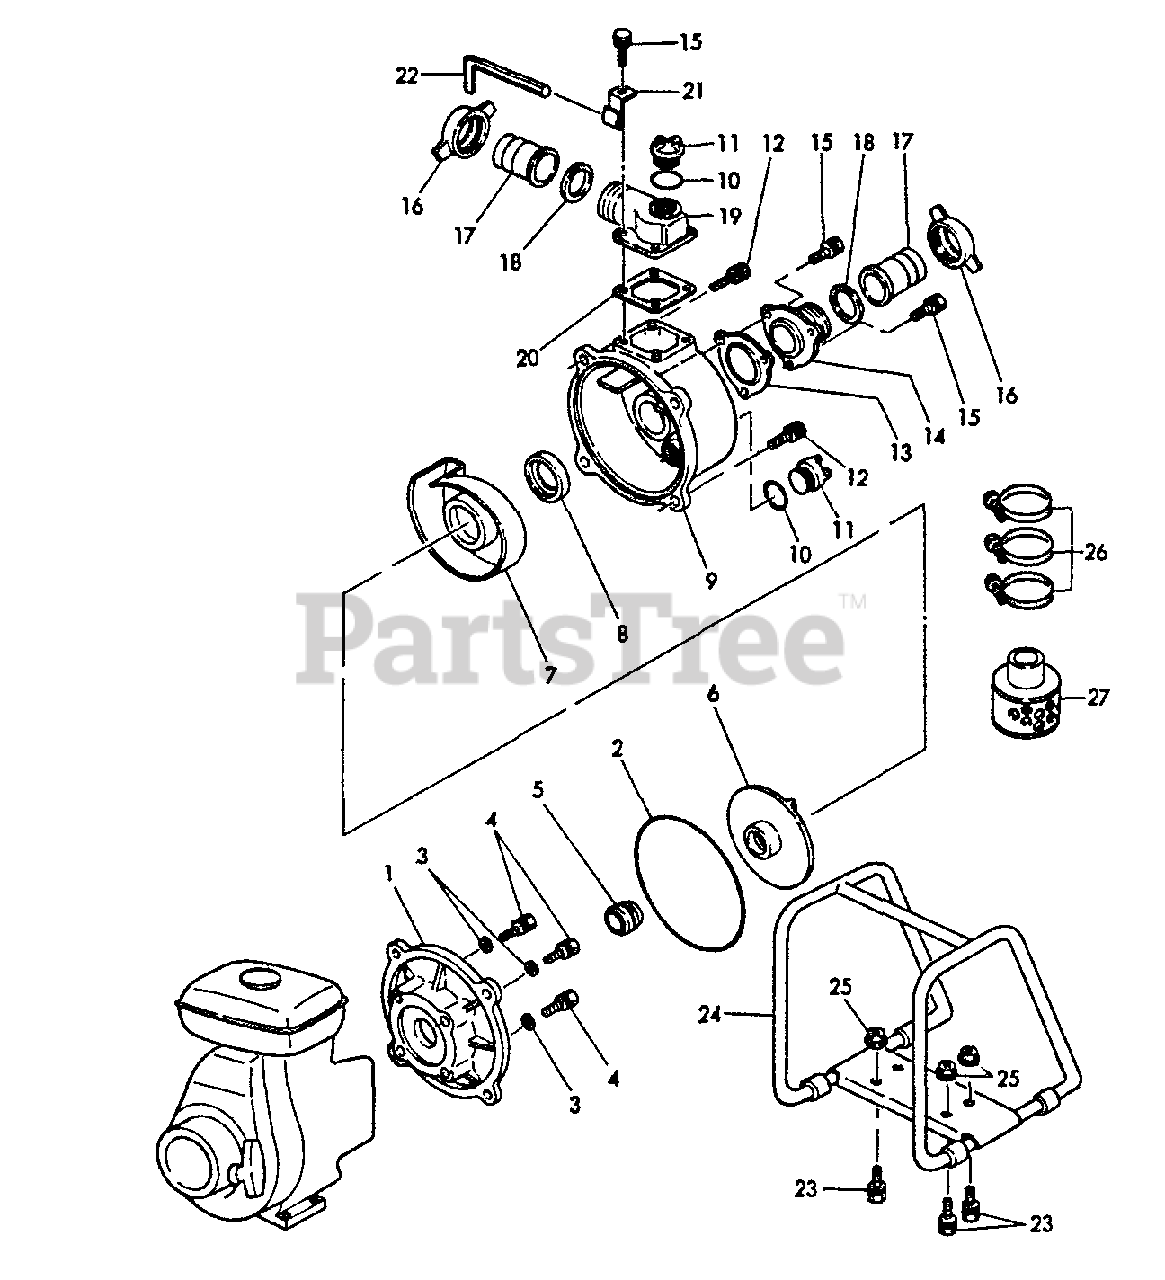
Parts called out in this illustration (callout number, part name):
1	COVER, PUMP CASE
2	GASKET, CASING
3	GASKET
4	BOLT - 8×48
5	SEAL, MECHANICAL
7	CASING, INNER, SHIM 0.8 Y50106200000
8	GASKET, INNER CASING
9	CASING
12	BOLT
13	VALVE, CHECK
14	CASE (NPT), VALVE
15	BOLT - 8×25
16	JOINT (AL-NPT), HOSE
17	COUPLING, HOSE
18	GASKET
19	BEND (NPT), DELIVERY
20	GASKET
21	HOOK
22	WRENCH, SOCKET
23	BOLT
24	FRAME
25	NUT - FLANGE
26	BAND, HOSE
27	STRAINER, DEBRIS
